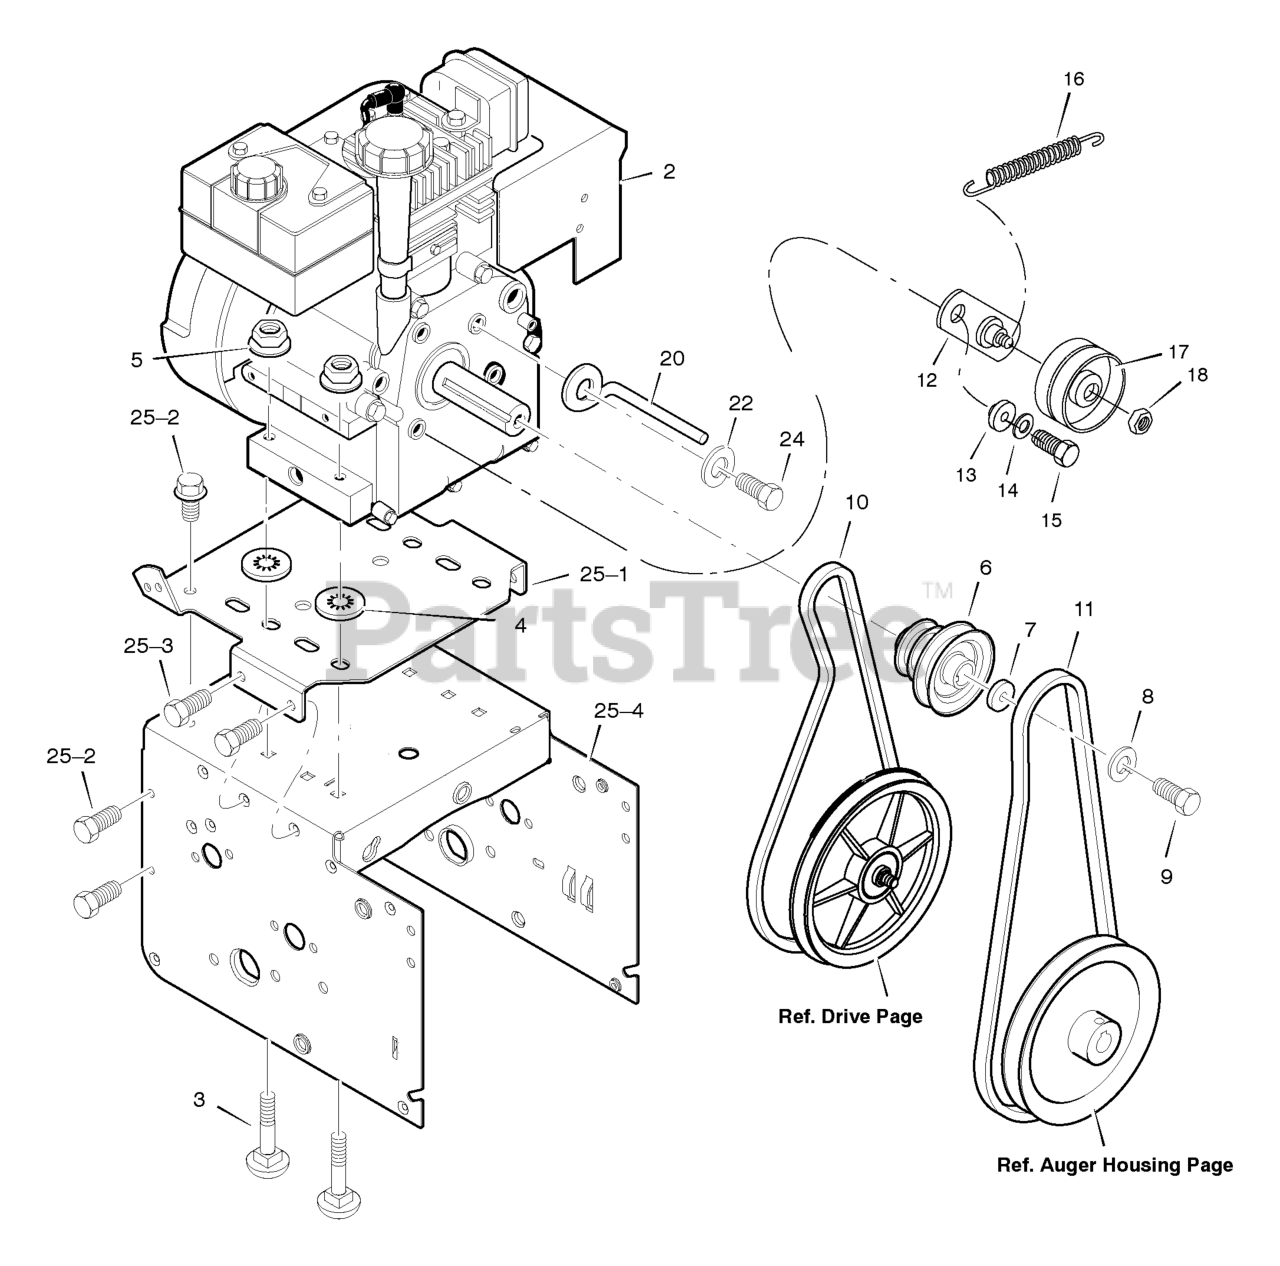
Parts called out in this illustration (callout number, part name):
2	Engine *
3	BOLT, CARRIAGE 5/16-18
4	RETAINER, PUSH
5	NUT 5/16-18
6	PULLEY, ENGINE
7	WASHER
8	WASHER .38ID
9	SCREW, 3/8-24 x 1.00
10	BELT, DRIVE V3L
11	BELT, AUGER V4L
12	BRACKET ASSEMBLY, IDLER
13	BUSHING, IDLER BRACKET
14	WASHER, SPLIT
15	SCREW 5/16-24 X 0.75
16	SPRING, IDLER TRACTION DRIVE
17	PULLEY, IDLER
18	NUT, JAM 3/8-16
20	GUIDE, BELT
22	WASHER .31X.58X.08
24	SCREW, 5/16-24 x 0.75
25-1	PLATE, ENGINE MOUNT
25-2	SCREW, TAP 1/4-20 X .63
25-3	SCREW, TAP 5/16-18 X .50
25-4	FRAME, MOTOR BOX
